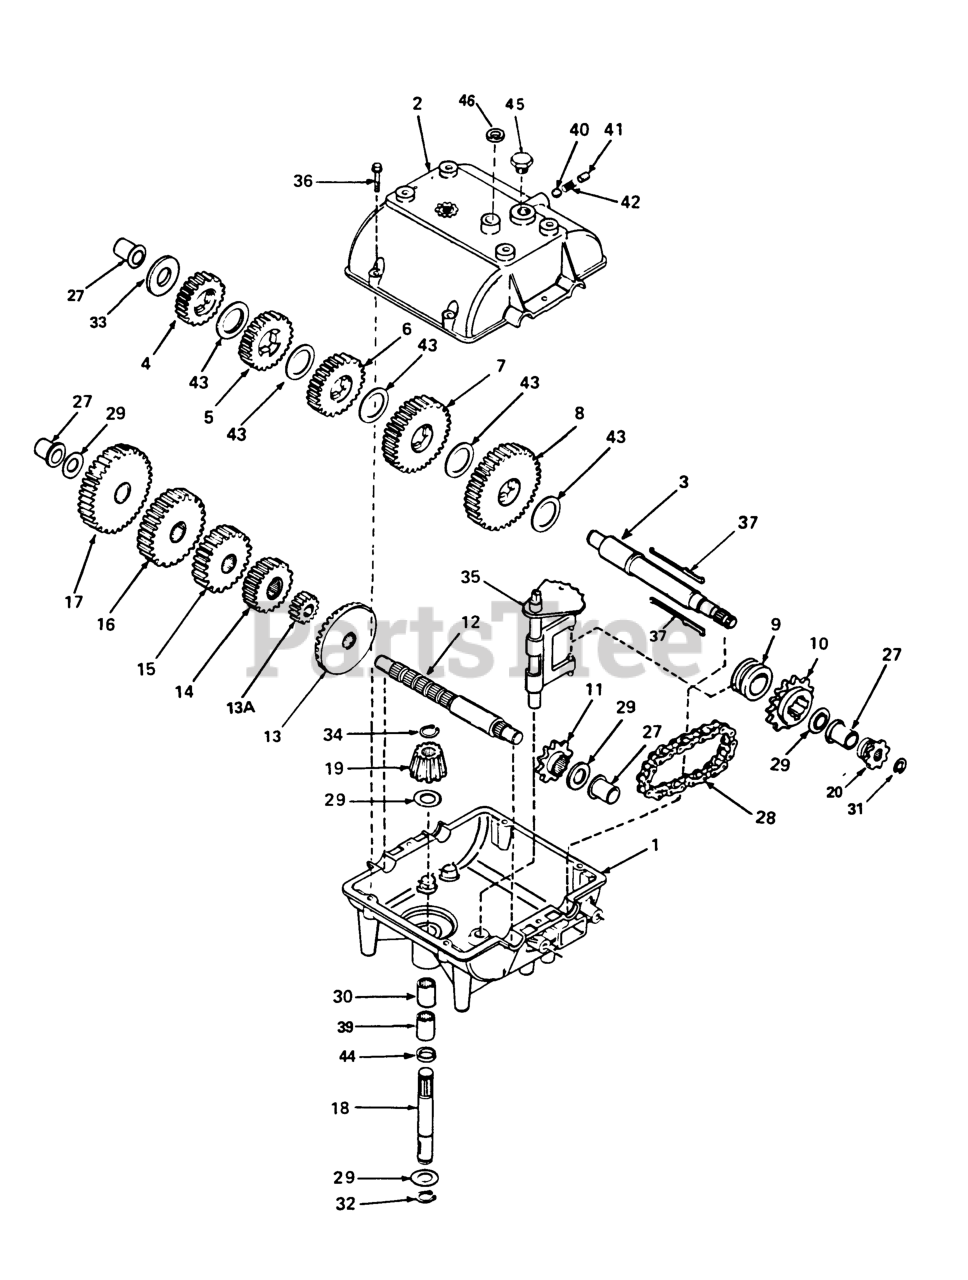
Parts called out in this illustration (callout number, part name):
1	Transmission Case
2	Cover, Transmission
3	Shaft, Output
6	Gear, Spur (25 Teeth)
7	Gear, Spur (30 Teeth)
8	Gear, Spur (35 Teeth)
9	Collar, Shift
10	Sprocket (18 Teeth)
11	Sprocket (9 Teeth Sprocket)
12	Shaft, Counter
13	Bevel Gear (42 Teeth)
13A	Gear, Spur (15 Teeth)
14	Gear, Spur (20 Teeth)
15	Gear, Spur (25 Teeth)
16	Spur (28 Teeth Gear)
18	Input Shaft (3-11/16" Long)
27	Bushing, Flanged
28	Chain, Roller (No. 41 Chain, 24 Links)
29	Washer, Thrust
30	Bearing, Needle
31	Ring, Retaining
32	Ring, Retaining
34	Ring, Retaining
35	Rod & Fork Assy., Shift
36	Screw, Flanged Hex Hd. Thr'd Forming 1/4-20 X 1-1/4
37	Shift Key
39	Bearing, Needle
40	Steel Ball, 5/16" Dia.
41	Set Screw, 3/8-16 X 3/8"
43	Washer, Thrust
44	"O" Ring
45	Plug, Threaded
46	Seal, Square Cut
